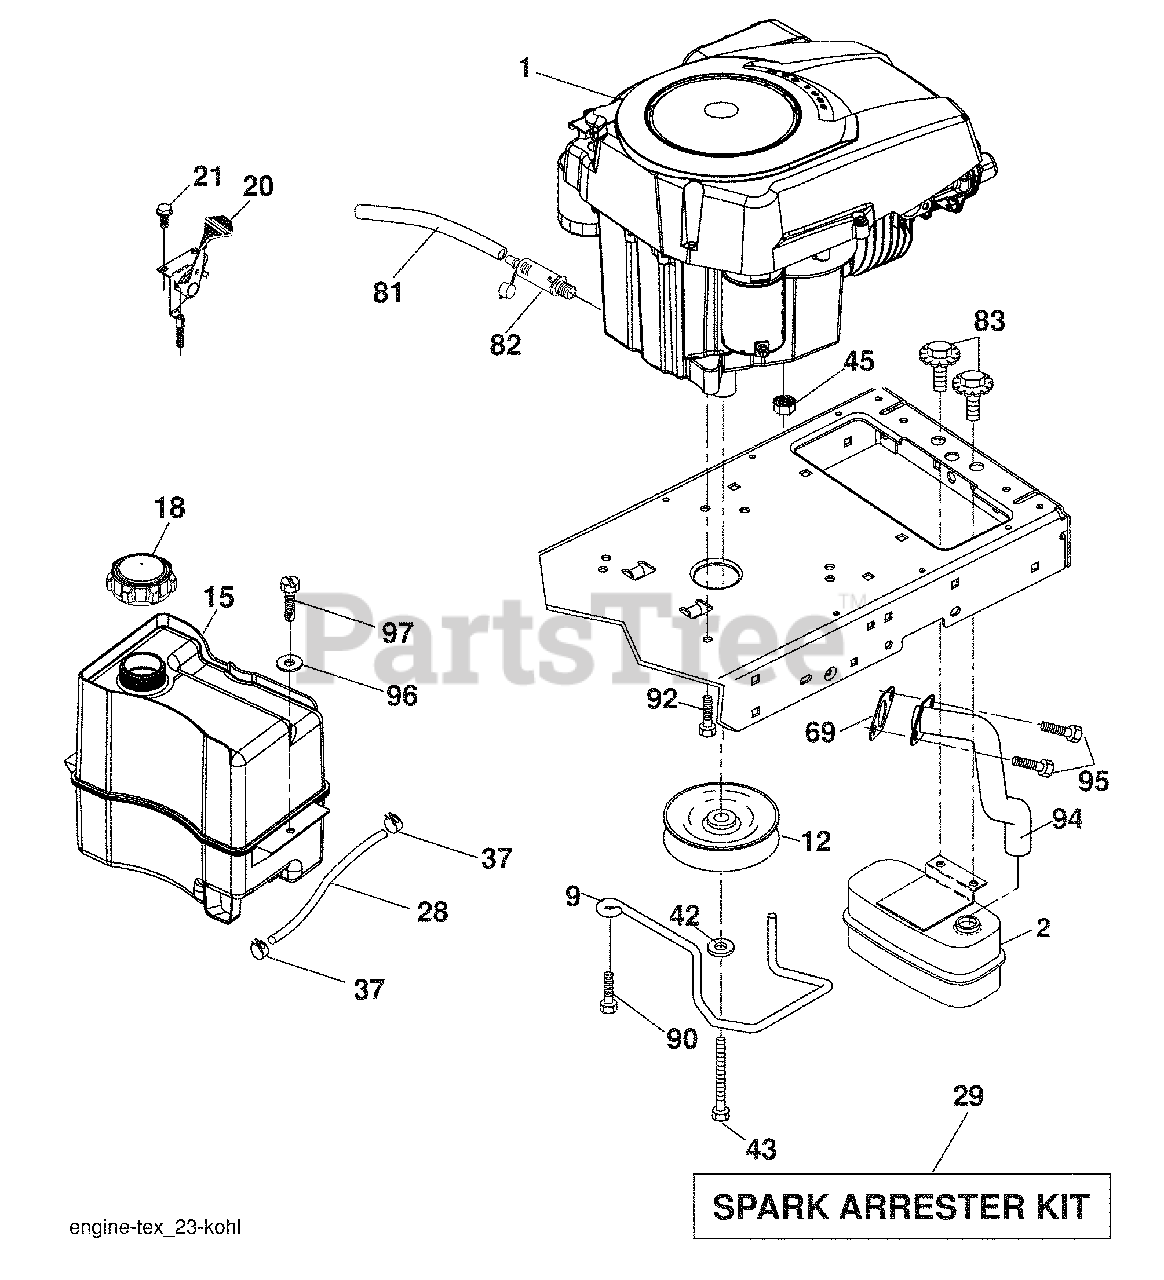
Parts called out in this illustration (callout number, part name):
9	Keeper Belt Engine
12	Pulley Engine
15	Tank Fuel
18	Cap Asm
20	Control Throttle
21	Screw 10 x 3/4 Single Lead-Hex
28	Fuel Line
29	Spark Arrester Kit
37	Clamp Hose
42	Washer Lock 7/16
43	Bolt Hex 7/16-20 x 4 Gr. 5
45	Nut Keps Hex 1/4-20 unc
69	Gasket
81	Tube Drain Oil Easy
82	Plug Drain Oil
83	Bolt 5/16-18 unc x 3/4 w/Sems
90	Screw 3/8-16 x 1
92	Screw 3/8-16 x 1
94	Tube Exhaust
96	Washer 9/32 x 7/8 x 16 Ga.
97	Screw 1/4-20 x 3/4
